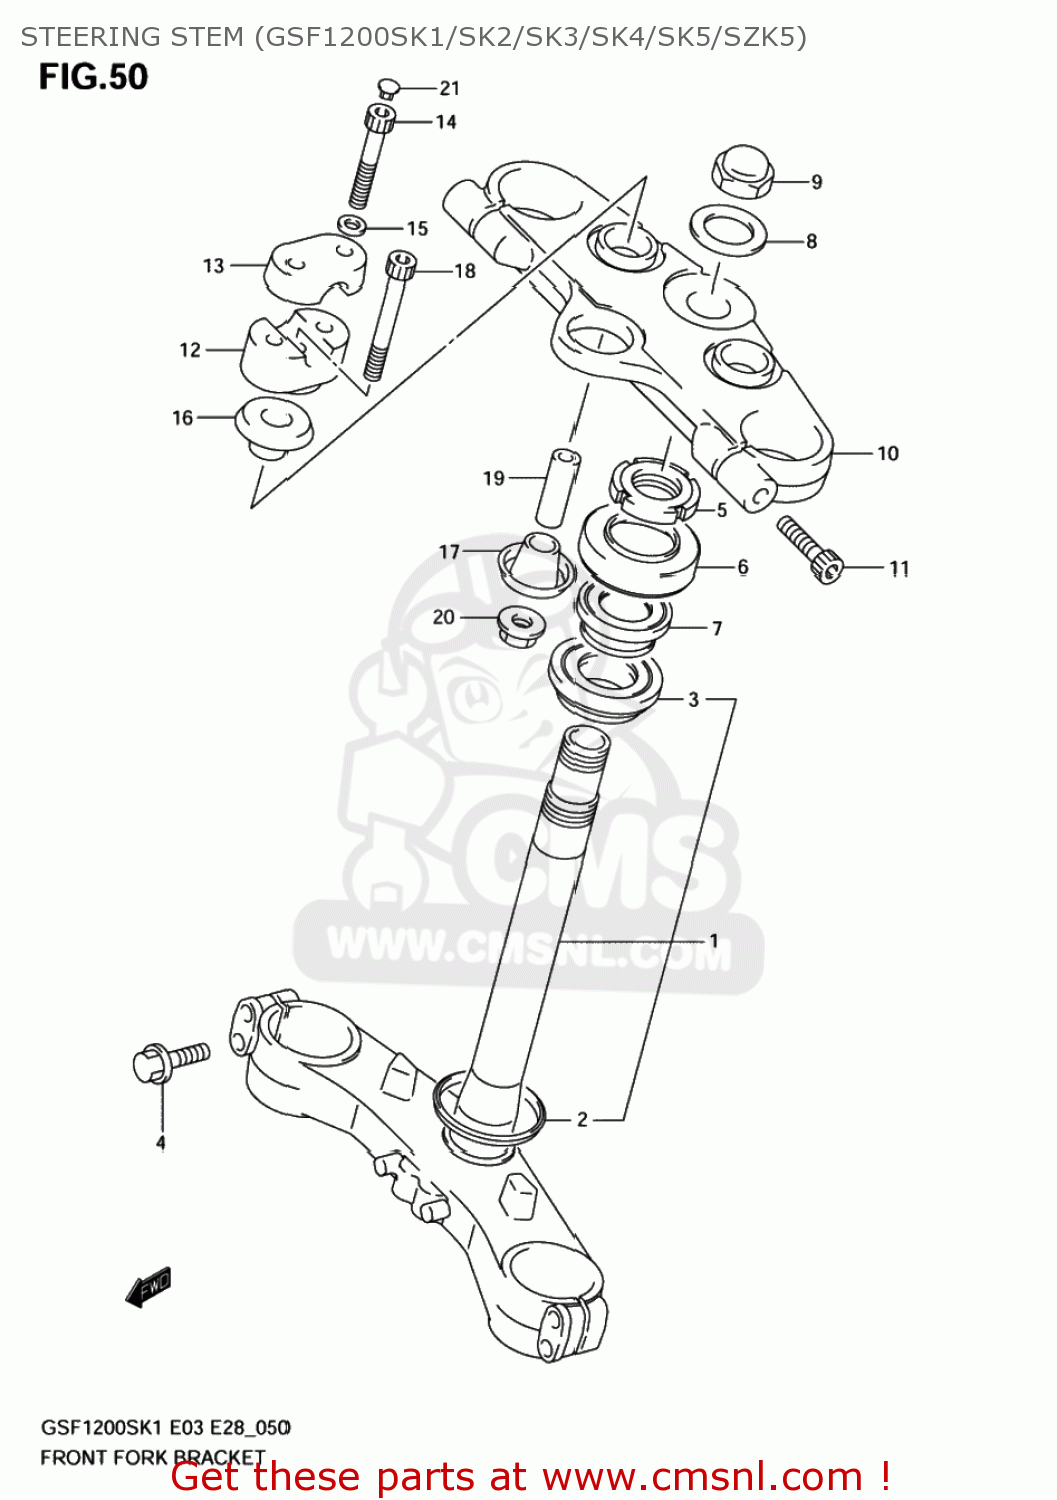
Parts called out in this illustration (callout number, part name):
1	STEM,STEERING
2	SEAL,STEERING LWR
3	BEARING(30X55X17)
4	BOLT
5	NUT,STEERING STEM
6	DUST SEAL,STEERING UPR
7	BEARING(25X47X15)
8	WASHER(22.5X32X1.6)
9	NUT,CAP
10	HEAD,STEERING STEM
11	BOLT
12	HOLDER,HANDLE UNDER
13	HOLDER,HANDLE UPR
14	BOLT
15	WASHER
16	CUSHION,RUBBER UPR
17	CUSHION,RUBBER UNDER
18	BOLT,HANDLE HOLDER(10X70)
19	SPACER
20	NUT
21	CAP(OD:11)
